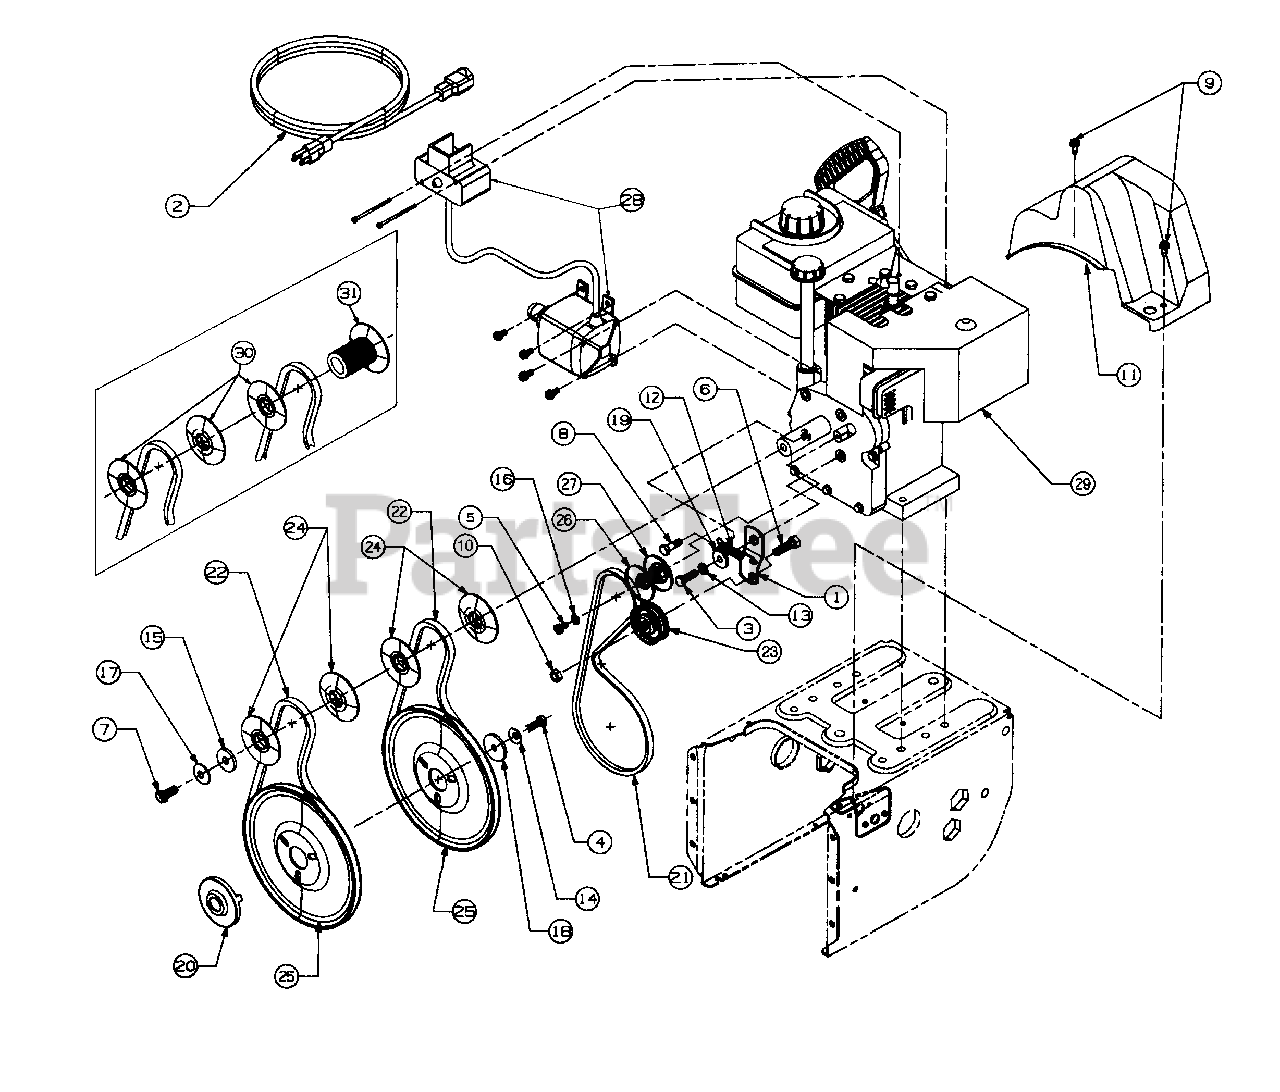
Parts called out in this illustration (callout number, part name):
3	Screw
4	Screw
5	Screw
6	Screw
7	Screw
8	Screw
9	Screw
10	Nut, Hex
11	Belt Cover
12	Spring
13	Washer-Flat
14	Washer-Bell
15	Washer-Flat
16	Washer-Lock
17	Washer-Bell
18	Washer-Flat
19	Shoulder Spacer
20	Pulley, Adapter
21	V-Belt
22	V-Belt Matched
23	Idler, Flat
24	Pulley, Half
25	Pulley-Auger
26	Pulley Half
27	Pulley Half
28	Starter
29	Engine
30	Pulley, Half
31	Pulley, Half
